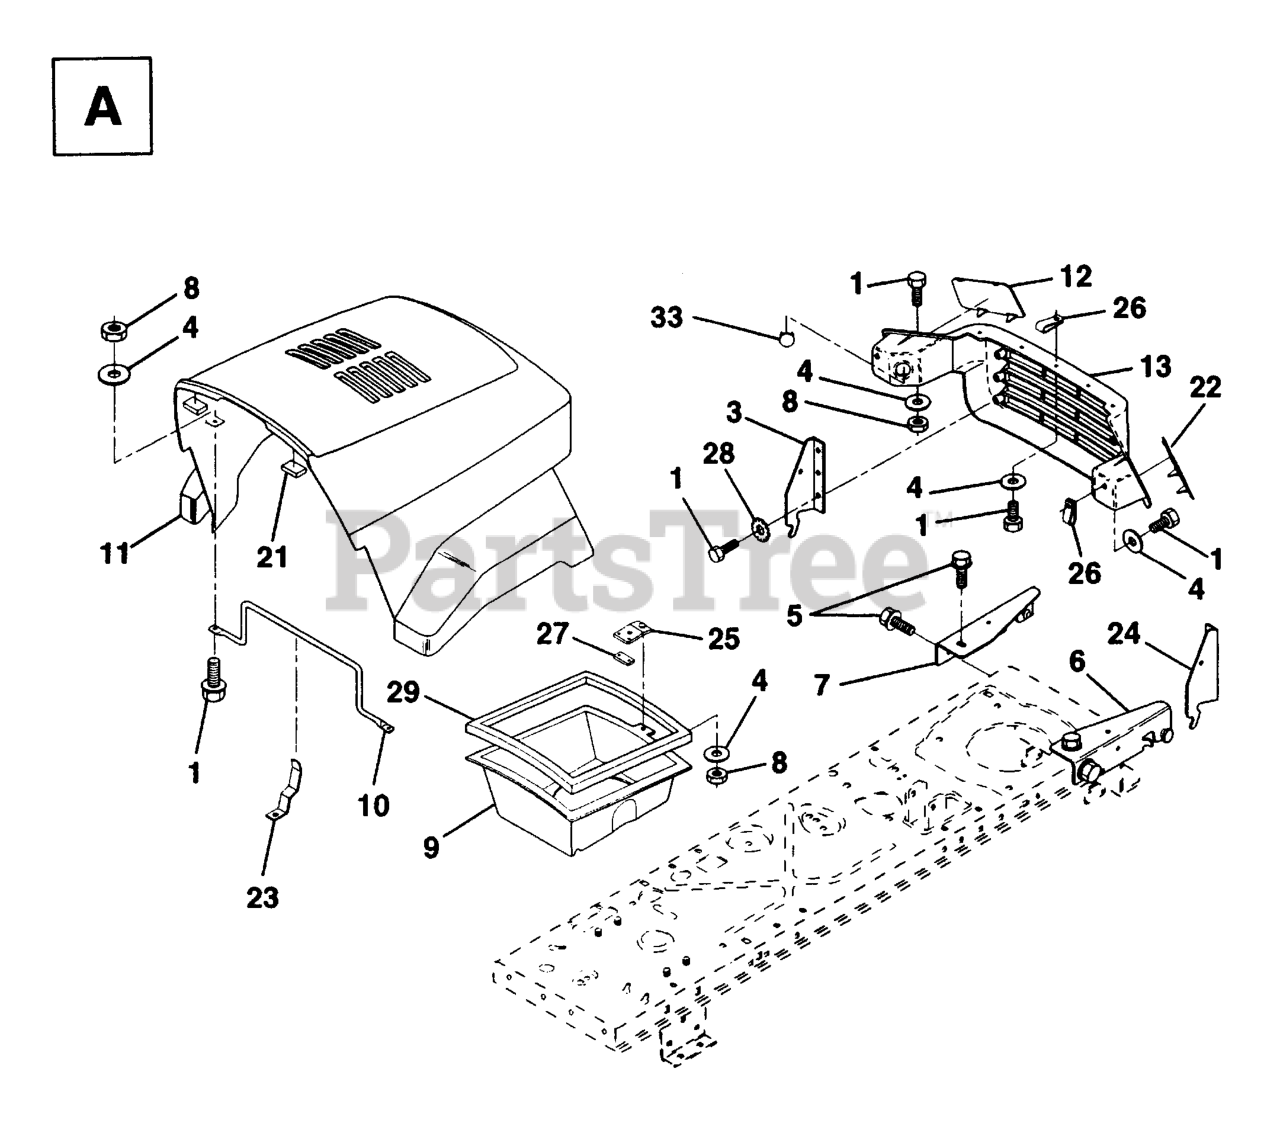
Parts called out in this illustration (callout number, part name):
1	BOLT
3	BRACKET HOOD
5	SCREW.THDROL.5/16-18X3/4.TTY
6	BRACKET ASSY HOOD
7	BRACKET ASSY
8	NUT
10	BRACE HOOD
12	LENS.LR.LH.HUSQV.
13	GRILL
21	BUMPER HOOD T
23	HOOD LATCH
24	BRACKET HOOD
26	CLIP TINNERMAN
28	Washer, Lock, External Tooth 1/4
29	FOAM STRIP LT
33	CVR LIGHT SOCKET
